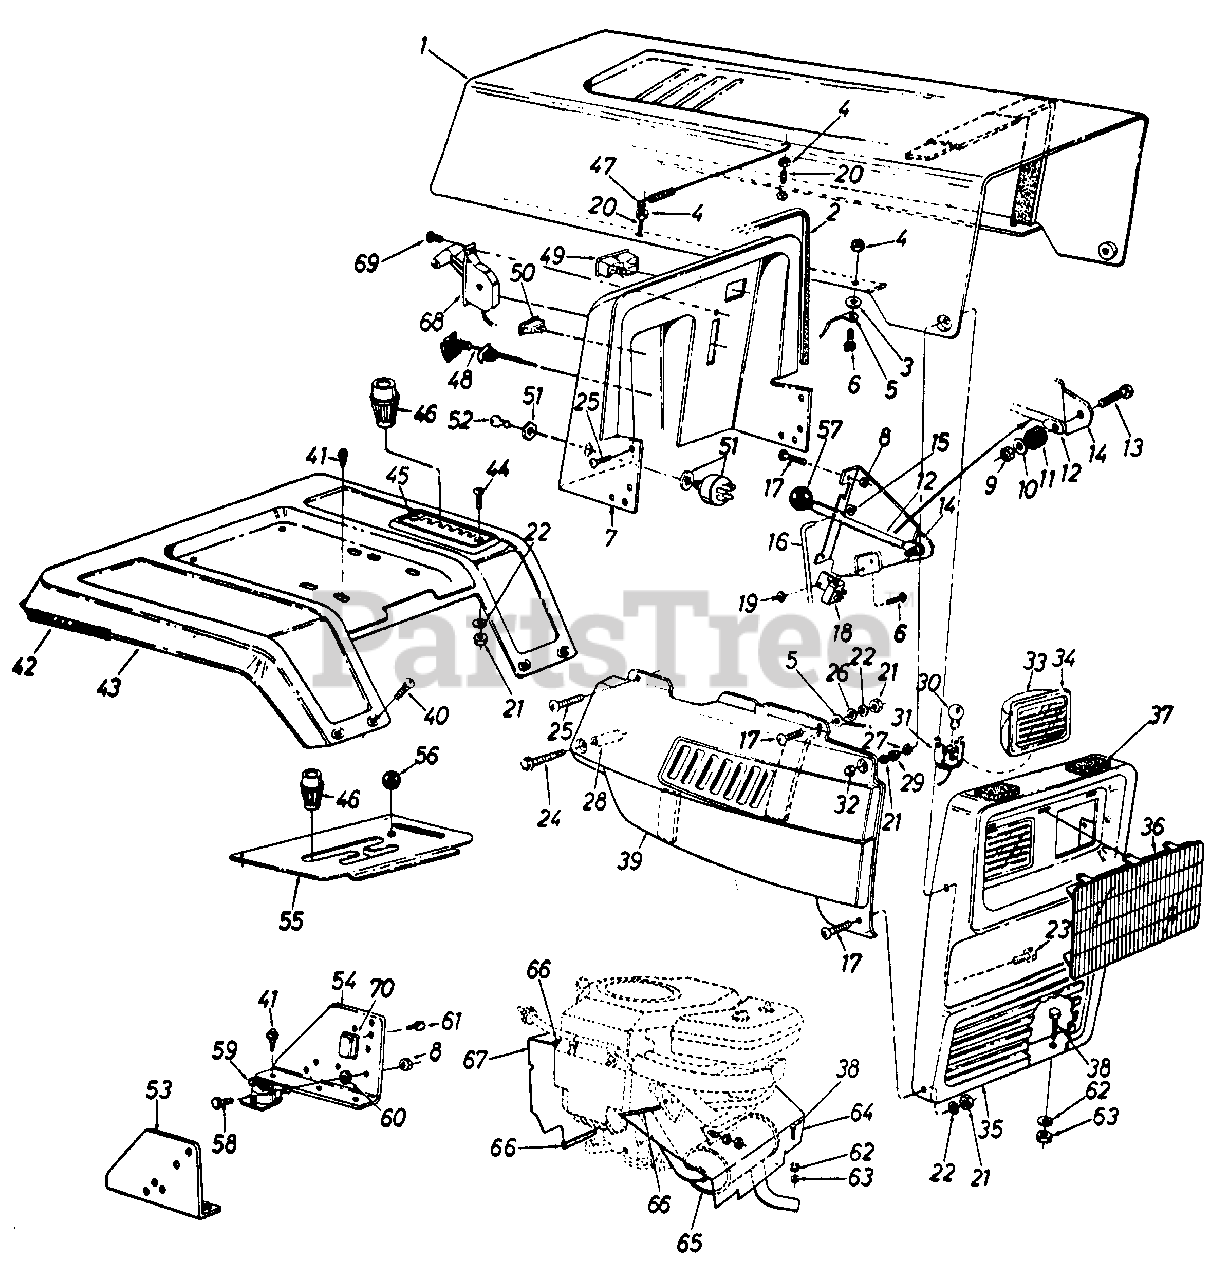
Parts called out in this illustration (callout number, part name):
3	Fl-Wash. .20" I.D. x 41" O.D.
4	Hex Sems Nut #10- 24 Thd.
5	Hood Stop
6	Truss Mach. Scr. #10-24 x .5" Lg.
9	Hex L-Nut 1/4-20 Thd.
10	Fl-Wash. .281" I.D. x .73" O.D.
11	Rubber Washer
12	PTO Lever
13	Hex Bolt 1/4-20 x 1.25" Lg.
14	Deck Clutch Control Brkt.
15	Push Cap
16	Deck Control Rod
17	Truss Mach. Scr. 1/4-20 x .5" Lg.
18	Safety Switch
19	Hex Nut #10-24 Thd.
20	Hex Bolt 10-24 x 1.0" Lg.
21	Hex Nut 1/4-20 Thd.
22	L-Wash. 1/4" I.D.
23	Hex Bolt 1/4-20 x .88n Lg.
24	Hex Wash. TT-Tap Scr. 1/4-20 x 1.75" Lg.
25	Hex TT-Tap Scr. 1/4-20 x .75" Lg.
26	Fl-Wash. 25n I.D. x .62"
27	Spr. Wash. .39" I.D. x .62"
28	Spacer .26" I.D. x .375"
29	Shld. Spacer .375" Dia. x .125" Lg.
30	Lamp
31	Socket
32	Acorn Nut 1/4-20 Thd.
33	Headlight Housing
34	Headlight Lens
37	Foam Strip
38	Hex Bolt 5/16-18 x .75" Lg.
41	Hex Wash. AB-Tap Scr. 5/16 x .75" Lg.
42	Trim Strip-81" Lg.
43	Fender
44	Truss Mach. Scr. 1/4-20 x .62" Lg.
45	7-Speed Selector Plate
46	Shift Knob
47	Hood Spring
48	Choke Control 46" Lg.
49	Ammeter
50	Light Switch
51	Ignition Switch
52	Ignition Key
53	Dash Support Brkt.-R.H.
54	Dash Support Brkt.-L.H.
55	Transmission Cover
56	Ball Knob
57	Knob-Blade Clutch
58	Hex Bolt 1/4-20 x 5" Lg.
59	Solenoid
60	Ext. L-Wash. 1/4" I.D.
61	Hex Wash. Hd. Scr. 1/4 x .5" Lg.
62	L-Wash. 5/16" I.D.
63	Hex Nut 5/16-18 Thd.
64	Front Heat Shield
65	Muffler
66	Trim Strip lon Lg.
67	Rear Baffle
68	Throttle Control Box Ass'y.
69	Truss Mach. AB-Tap Scr. #10 x .5" Lg.
70	Circuit Breaker
